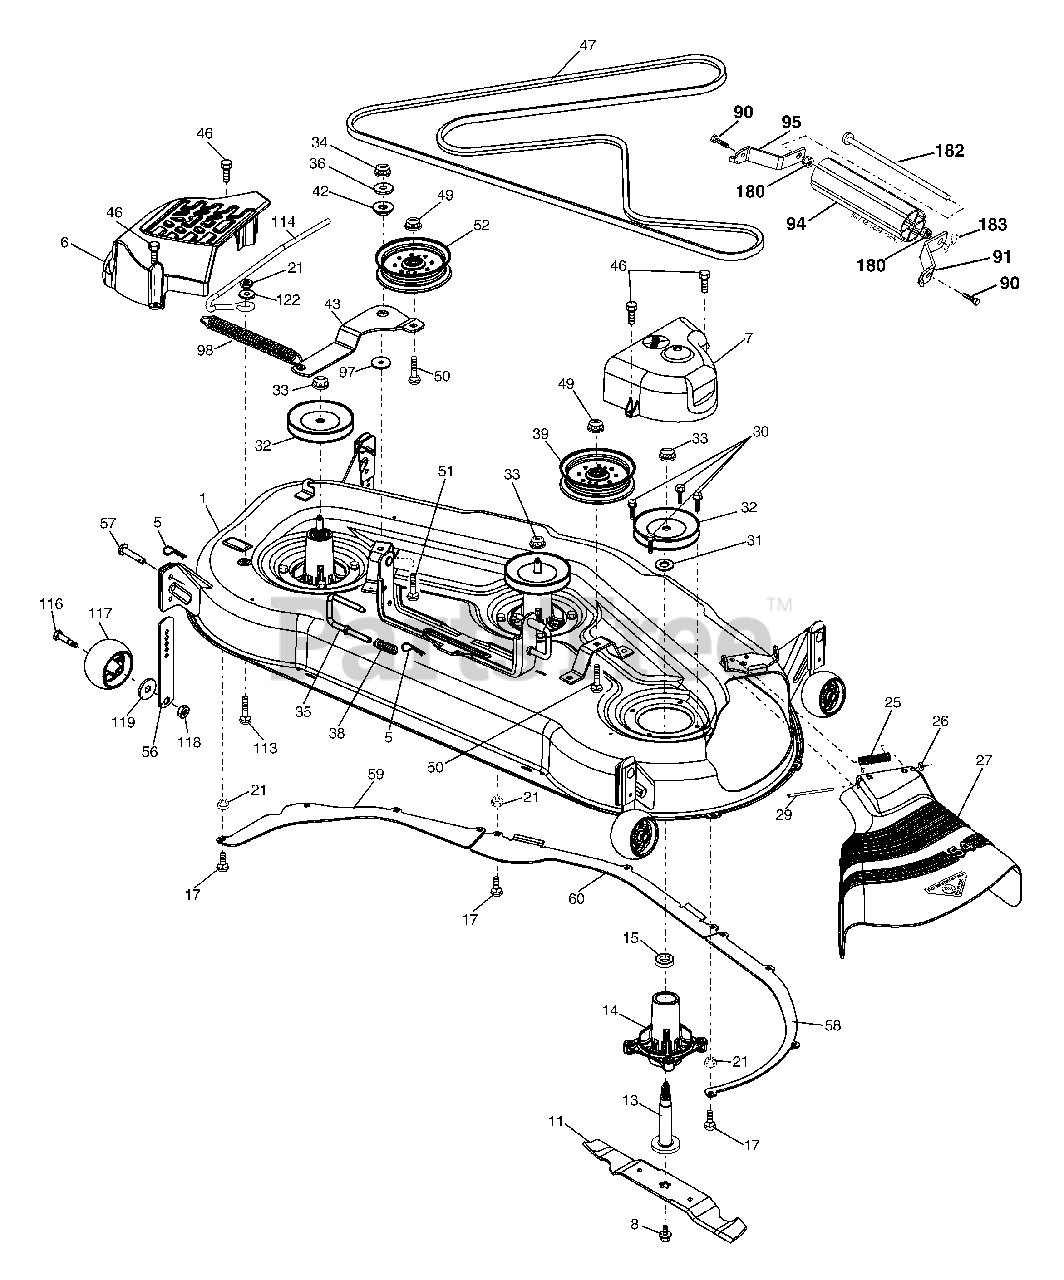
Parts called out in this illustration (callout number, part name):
1	Deck Weldment Mower
5	Retainer Spring
6	Cover Mandrel LH
7	Cover Mandrel RH
8	Bolt 7/16 Asm. Blade
11	Blade Standard
13	Shaft Asm. w/Lower Bearing
14	Mandrel Housing
15	Bearing, Ball, Mandrel
17	Bolt Carr. 5/16-18 x 5/8
21	Nut, Crownlock 5/16-18 unc
25	Spring Torsion
27	Deflector Shield
28	Washer 11/32 x 5/8 x 16 Ga.
29	Rod, Hinge
30	Screw Thd Roll
31	Washer, Spacer Mower Vented
32	Pulley, Mandrel
33	Nut, Flg. Top Lock Cntr. 9/16
35	Pin Suspension Rear
36	Washer 13/32 x 13/16 x 16 Ga.
38	Spring Compression
39	Pulley, Idler, Stationary
41	Bushing Relief Tension
42	Spacer, Retainer
43	Arm, Idler
46	Screw, Thdroll. 1/4-20 x 5/8
47	V-Belt, Mower, Secondary
49	Nut, Lock Flg. 3/8-16 unc
50	Bolt, Carr. 3/8-16 x 2
51	Bolt 3/8-16 x 1-1/4 Gr. 5
52	Pulley Idler clutching
56	Bar Pnt Adj.
57	Pin Head Rivet
58	Baffle Right
59	Baffle Left
60	Baffle Center
90	Bolt 5/16-18 x 1
91	Bracket Asm N Roller RH
94	Roller Nose 48"
95	Bracket N Roller LH
97	Washer Hardened
98	Spring Clutch Drive
101	Cover Mulching
102	Screw 10-24 x 5/8
103	Washer Lock
105	Nut Weld
113	Bolt Rdhd Sqnk 5/16-18 unc x 3/4
114	Rod Tension Relief
116	Bolt, Shoulder
117	Gauge Wheel
118	Nut, Centerlock 3/8-16 unc
119	Washer 3/8 x 7/8 x 14 Ga.
122	Bushing Tension Relief
180	Nut 5/16-18
182	Rod Roller Nose Narrow
183	Retainer Spring
